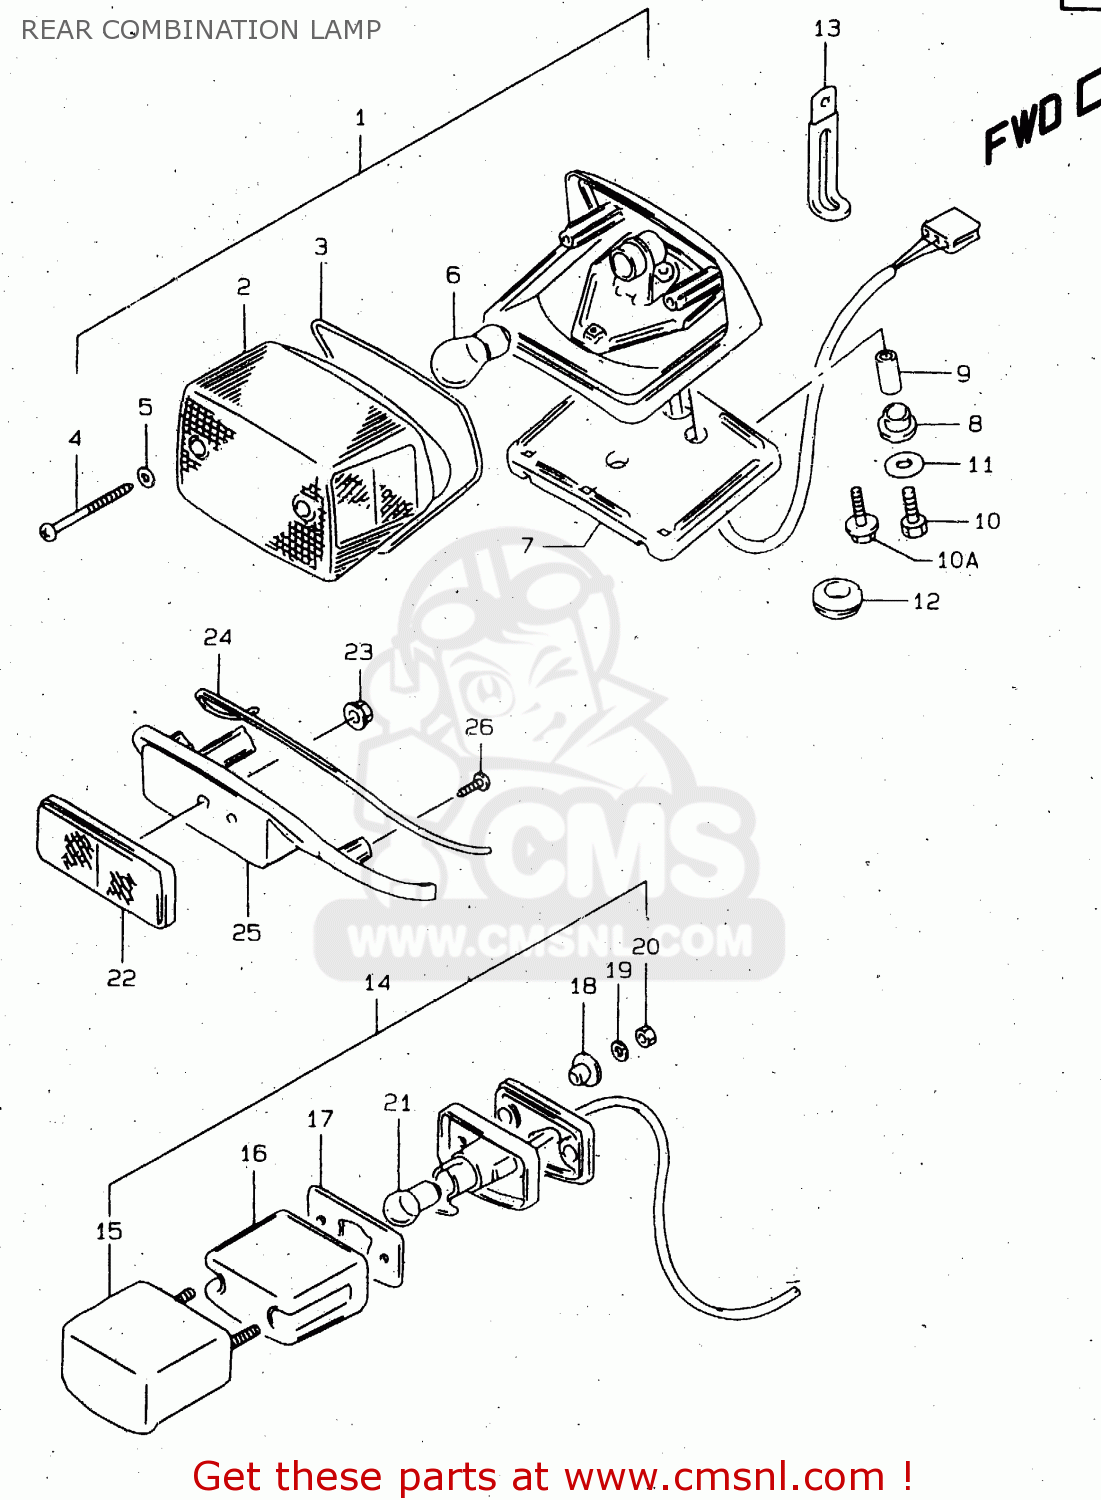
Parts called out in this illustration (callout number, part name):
1	LAMP ASSY,RR COMBINATION
2	LENS
3	GASKET (NAS)
4	SCREW
5	GASKET (NAS)
6	BULB(12V21/5W)
7	CUSHION
8	CUSHION
9	SPACER,COMBINATION LAMP
10	BOLT
10A	BOLT(6X30)
11	WASHER
12	GROMMET
13	CLAMP(L:65)
14	LAMP ASSY,LICENSE
15	COVER,LICENSE LAMP
16	LENS
17	GASKET,LICENSE LAMP (NAS)
18	SPACER
19	WASHER,LOCK
20	NUT
21	BULB(12V5W,BF150-40160A)
22	REFLECTOR ASSY,RR
23	NUT
24	CUSHION
25	SPACER,RR RR
26	SCREW
